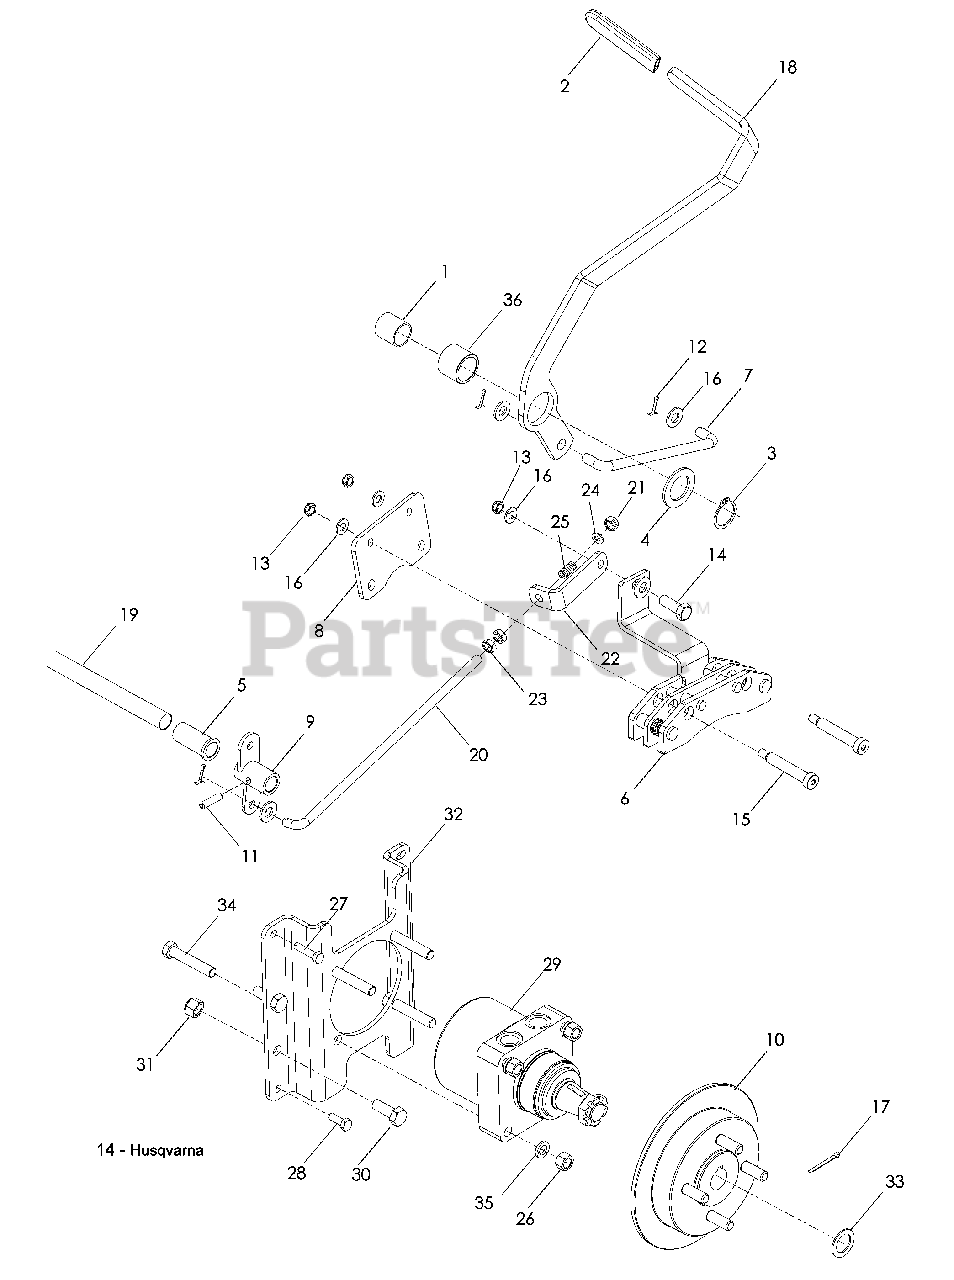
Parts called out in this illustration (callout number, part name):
3	RING, RETAINING 7/8
4	BUSHING, MACHINE
5	BUSHING, POLYMER ¾ x 2
7	LINKAGE, BRAKE
8	PLATE, BRAKE
9	BELLCRANK, BRAKE
11	PIN, ROLL 5/16"
12	PIN, COTTER 3/32 x ¾
13	NUT 3/8-16 JAM, NYLOC
14	HCS 3/8-16 x 1
15	SB 3/8-16 x 2½ SKT HD
16	WASHER 3/8 SAE FLT
17	PIN, COTTER
18	LEVER, BRAKE
19	SHAFT, CROSS
20	LINKAGE, REAR BRAKE
21	NUT 3/8-24 CTR LK
22	BRACKET, L
23	NUT 3/8-24 JAM
24	WASHER 3/8 SAE
26	NUT ½-13 HEX
27	HCS 3/8-16 x 1¼
28	HCS 3/8-16 x 2¼
29	WHEEL MOTOR, TL15
30	HFCS ½-13 x 1¼ WHIZLK
31	NUT ½-13, NYLOC
32	MOUNT, WHEEL MOTOR
33	BUSHING, MACHINE
34	HCS ½-13 x 2¾
35	WASHER ½ SLW
36	TUBE, BRAKE LEVER
